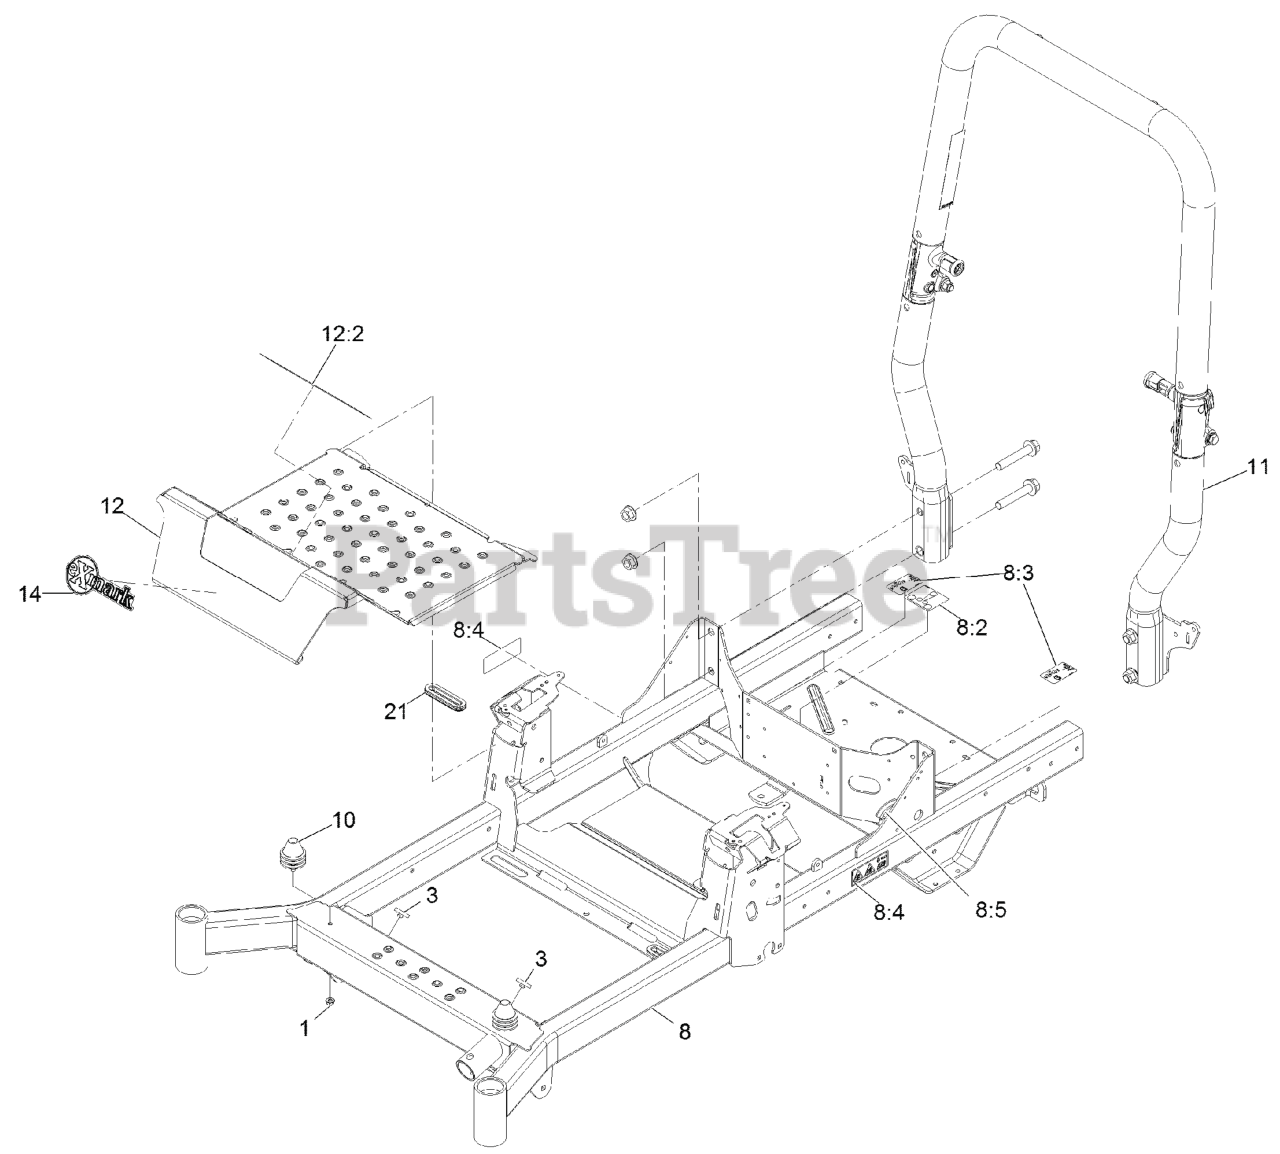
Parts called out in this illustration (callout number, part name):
1	NUT-HF, NI
3	BUMPER-PUSH-IN, RUBBER
8	FRAME ASM
8:2	DECAL-ROUTING, BELT
8:3	DECAL-RELEASE, DRIVE
8:4	DECAL-WARNING
8:5	STRIP-SEAL
10	ISOLATOR
11	ASM-ROPS TAPERED
12	PAN-FLOOR
12:2	DECAL-DANGER
14	DECAL-EXMARK LOGO
21	GROMMET-RUBBER
